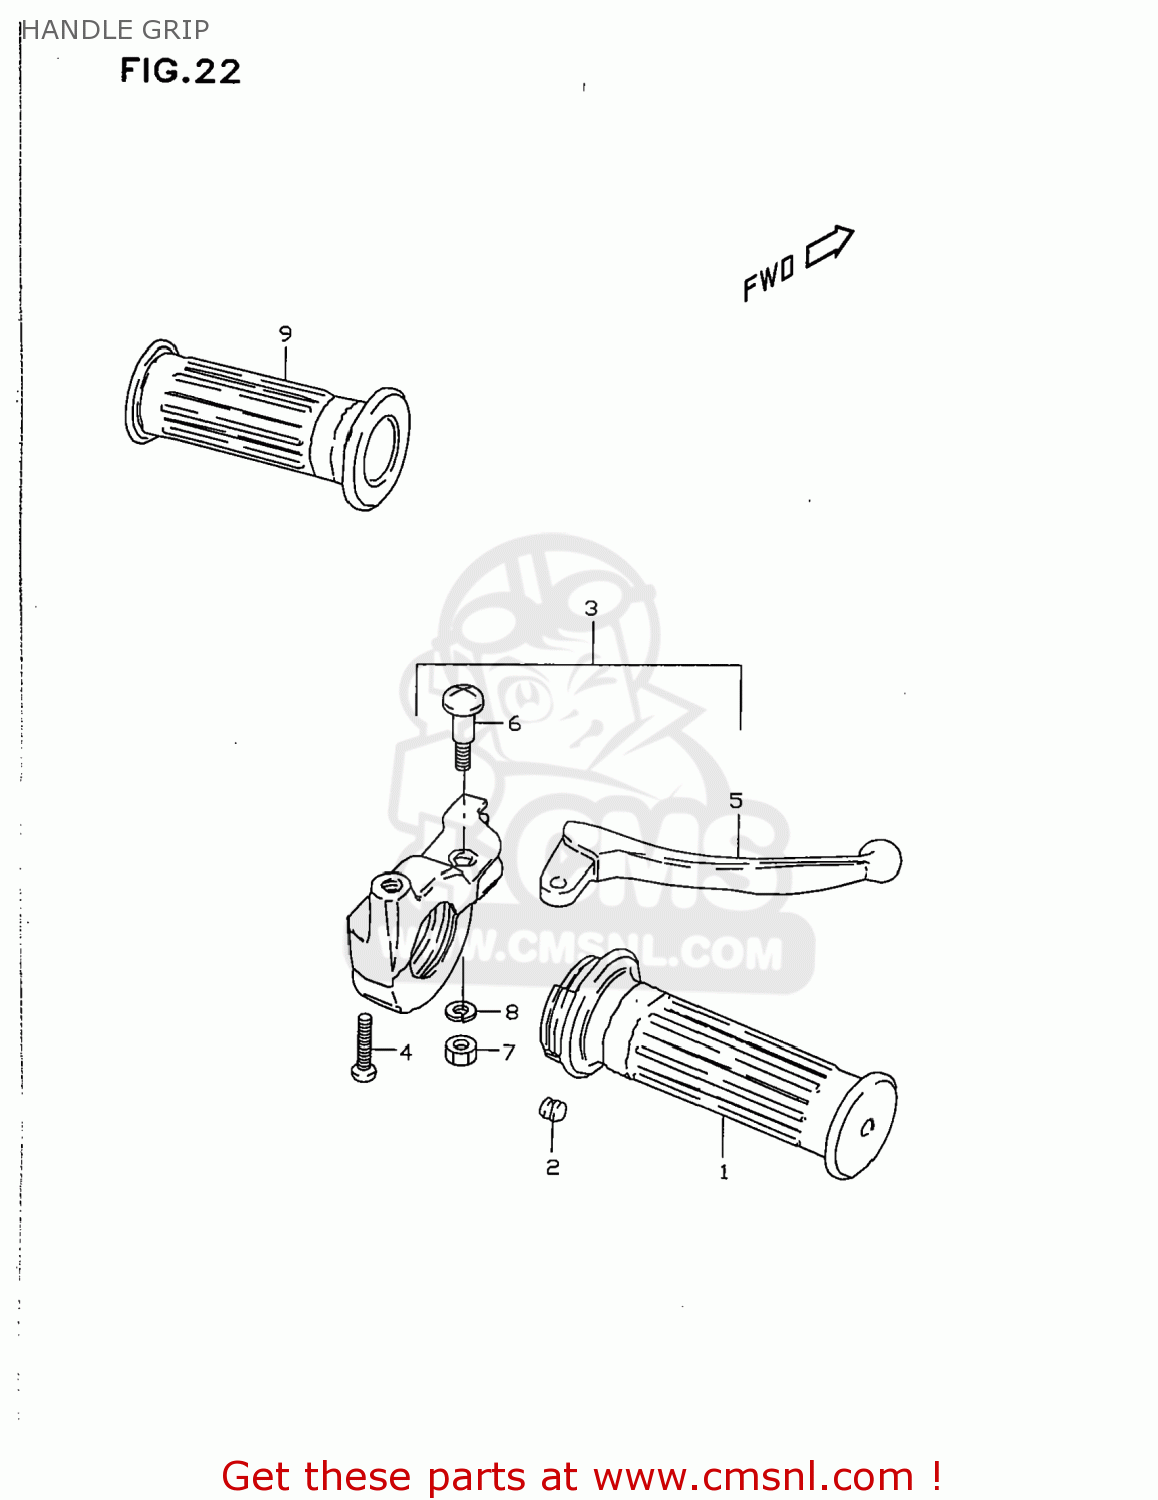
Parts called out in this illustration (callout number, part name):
1	GRIP,THROTTLE
2	PIECE,THROTTLE END
3	LEVER ASSY,BRAKE
4	SCREW(5X22)
5	LEVER,BRAKE
6	SCREW,BRAKE LEVER PIVOT
7	NUT
8	LOCK,WASHER
9	GRIP,L
